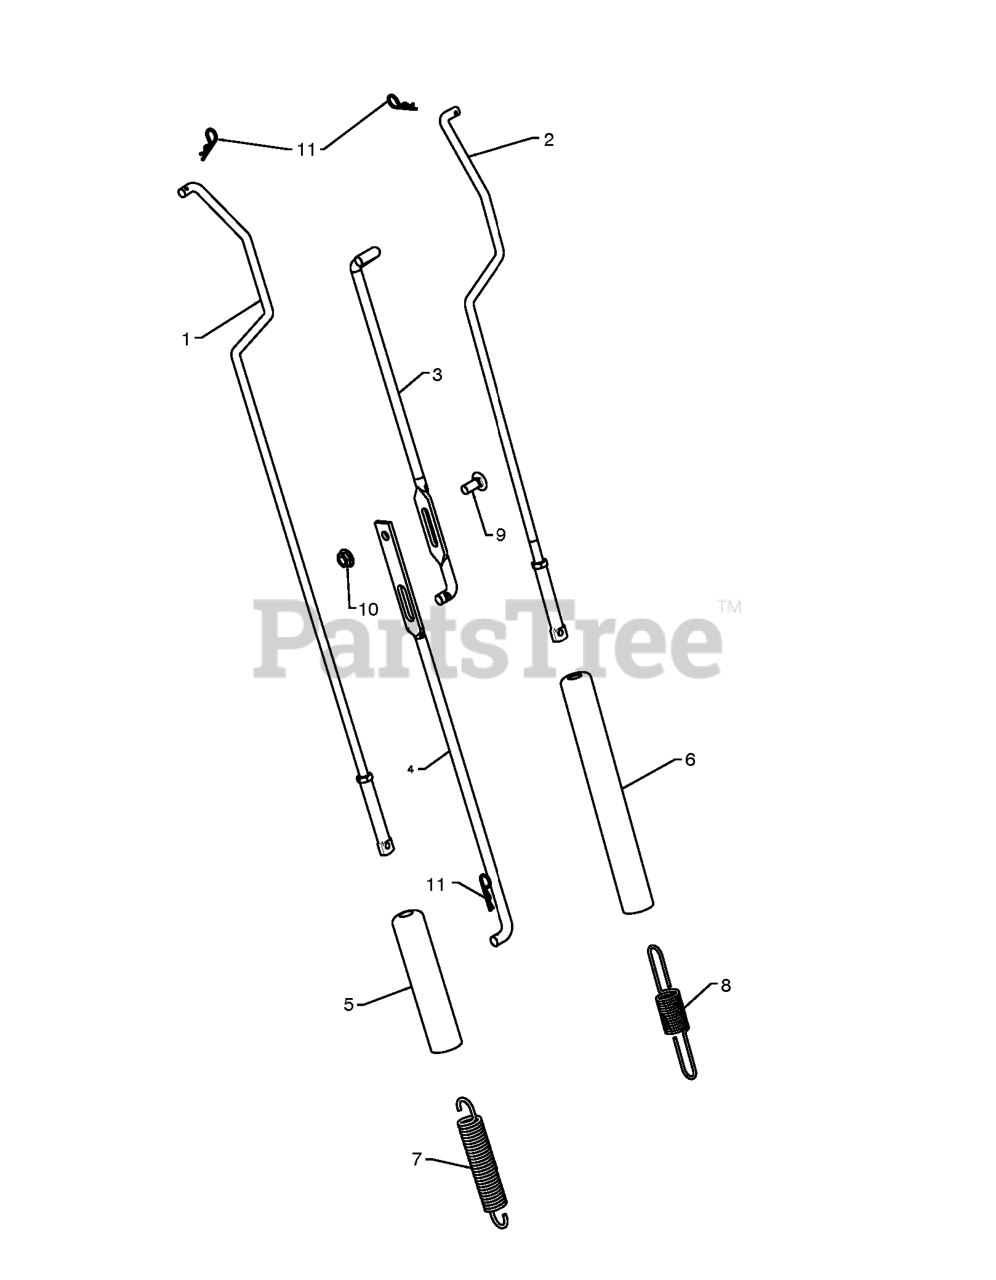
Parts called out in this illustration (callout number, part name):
1	ROD.ASM.IMPELLER.HYD
2	TRACTION ROD ASSY.
3	ROD.SHIFTER.TOP.HYD.SNOW
5	SLEEVE, SPRING
6	SLEEVE, SPRING
7	SPRING, AUGER CONTROL
8	SPRING, TRACTION DRIVE
9	BOLT
10	NUT.FLANGE.5/16
11	SPRING RETAINER
